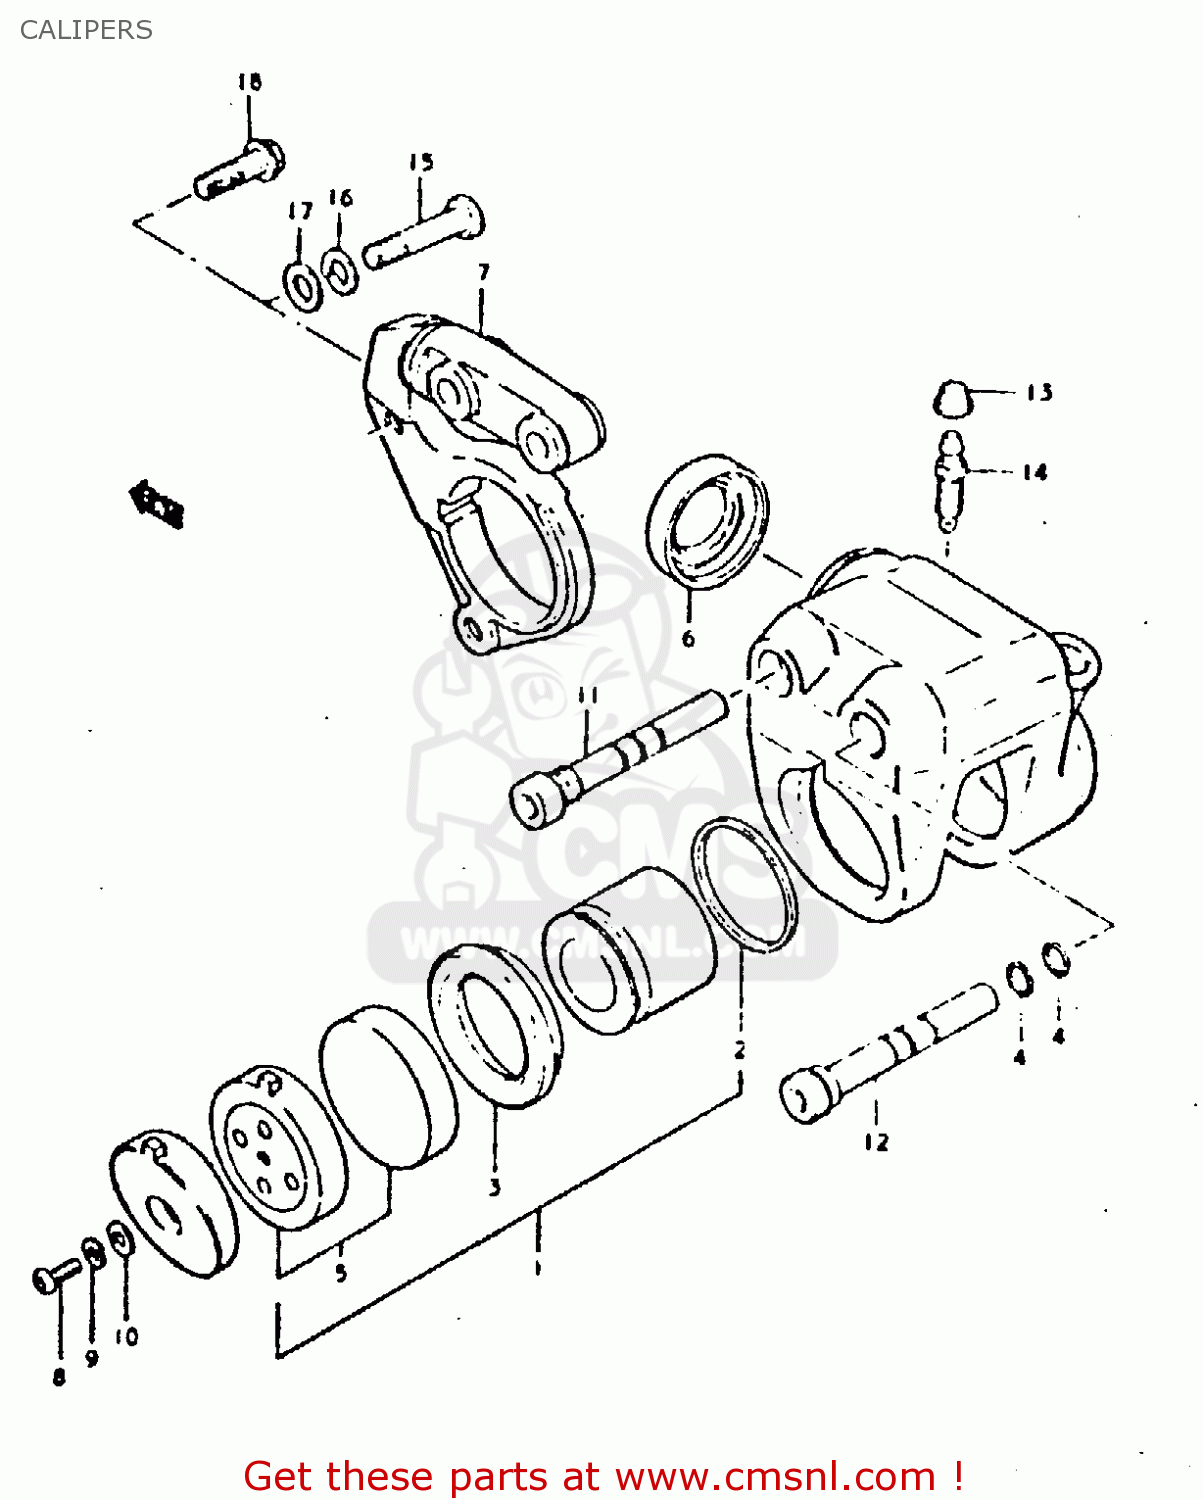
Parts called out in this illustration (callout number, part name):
1	PISTON & PAD SET
2	SEAL,PISTON
3	BOOT,PISTON
4	O RING,AXLE CALIPER
5	PAD SET,BRAKE (MCA)
6	BOOT,HOLDER
7	HOLDER,CALIPER
8	SCREW
9	LOCK WASHER
10	WASHER
11	AXLE,CALIPER
12	AXLE NO.2
13	CAP,BLEEDER PL
14	BLEEDER
15	BOLT
16	LOCK WASHER
17	WASHER
18	BOLT(10X37)
